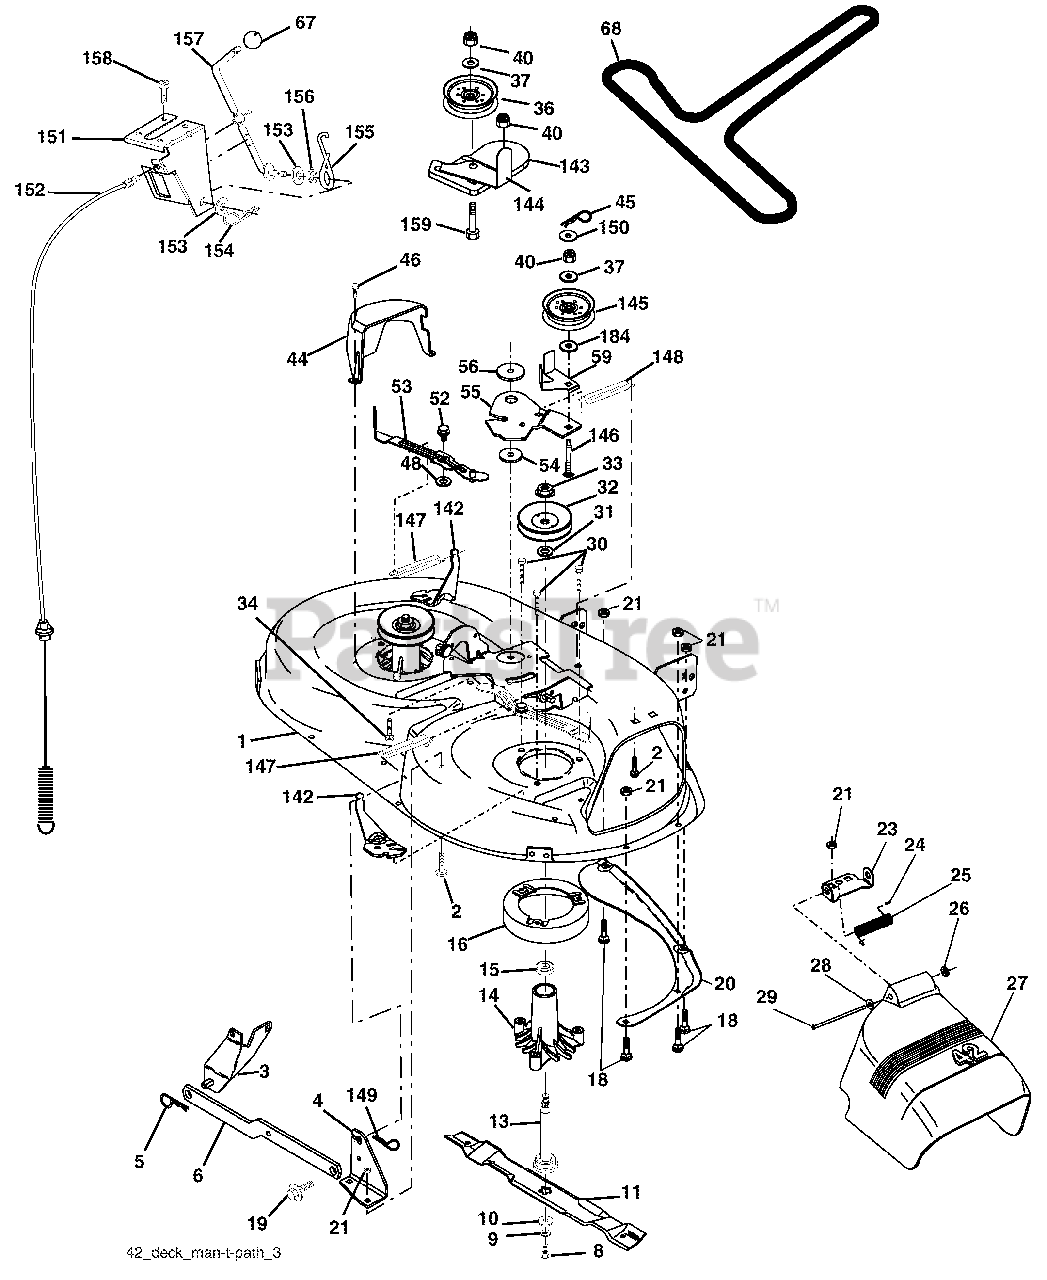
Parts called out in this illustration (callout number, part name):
1	Mower Deck Assembly, 42"
2	Bolt
3	Bracket Asm Fr. Sway Bar 3/42
4	Bracket Asm Deck 42" Sway Bar
5	Retainer Spring
6	Bar Sway Deck
8	Bolt 3/8-24 x 25 Grade 8 patched
9	Washer, Lock
10	Washer, Hardened
11	Blade, 42" Mulching Std
11	Blade, 42" Mulching Premium
11	Blade, 42" Hi-Lift
13	Shaft Assembly, Mandrel, Vented
14	Housing, Mandrel, Vented
15	Bearing, Ball, Mandrel
16	Stripper, Vented Mower Deck
18	Bolt, Carriage 5/16-18 x 5/8
19	Bolt, Shoulder
20	Baffle, Vortex
21	Nut
23	Bracket, Deflector Mower 42"
24	Cap, Sleeve 80 x 112 Blk Mower
25	Spring, Torsion, Deflector 2 52
26	Nut, Push Phos & Oil
27	Shield, Deflector 42" Blk
28	Washer 11/32 x 5/8 x 16 Ga.
29	Rod, Hinge 42" 6 75 W/G
30	Screw Thdrol Washer Head
31	Washer, Spacer Mower Vented
32	Pulley, Mandrel
33	Nut, Toplock Flange
34	Bolt
36	Pulley, Idler, Flat
37	Washer 13/32 x 13/16 x 16 Ga.
40	Nut
44	Guard, Mandrel, LH
45	Retainer
46	Screw, Thdrol 1/4-20 x 5/8 T
48	Washer, Hardened
52	Bolt, Shoulder 5/16-18 Unc
53	Arm Assembly, Pad, Brake
54	Washer, Hardened
55	Arm, Idler
56	Spacer, Retainer
59	Guard TUV Idler
67	Knob
68	V-Belt, 42" Mower
142	Arm Spring Brake Mower
143	Bracket Arm Idler 42"
144	Keeper Belt 42" Clutch Cable
145	Pulley Idler Flat
146	Bolt Carriage Idler
147	Spring Extension
148	Spring Return Idler
149	Retainer Spring Yellow
150	Washer 9/32 x 3/4 x 16 Ga.
151	Bracket Clutch Cable
152	Clutch Cable 42"
153	Washer Flat 3/8" Type B
154	Spring Retainer
155	Spring Retention LVR CLTCH CAB
156	Spacer Clutch Cable
157	Rod Clutch Cable 3/8"
158	Screw Hex Thd Cut 1/4-20 x 1/2
159	Bolt Rdhd Sqn 3/8-16 Unc x 1-3/4
184	Washer 13/32 x 7/8 x 10 Ga.
